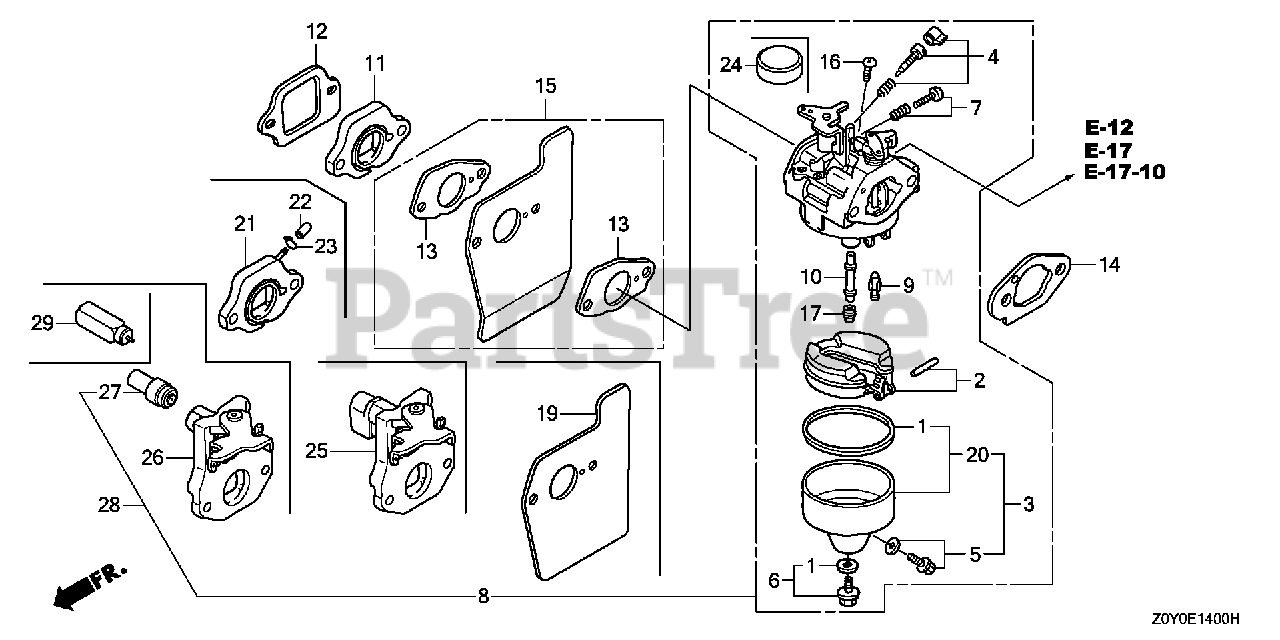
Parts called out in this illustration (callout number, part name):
1	GASKET SET
3	CHAMBER SET, FLOAT (CARBURETOR NO.)
4	SCREW SET (CARBURETOR NO.)
5	SCREW SET, DRAIN (CARBURETOR NO.)
6	SCREW SET
7	SCREW SET (THROTTLE STOP) (CARBURETOR NO.)
8	CARBURETOR ASSY. (BB65C A)
9	VALVE, FLOAT (CARBURETOR NO.)
10	NOZZLE, MAIN
11	INSULATOR, CARBURETOR
12	GASKET, INSULATOR
13	GASKET, CARBURETOR
14	GASKET, CARBURETOR
15	GUIDE, AIR
16	SCREW, PAN (5X6)
17	JET, MAIN (#65)
17	JET, MAIN (#68)
17	JET, MAIN (#70)
20	CHAMBER SET, FLOAT (CARBURETOR NO.)
